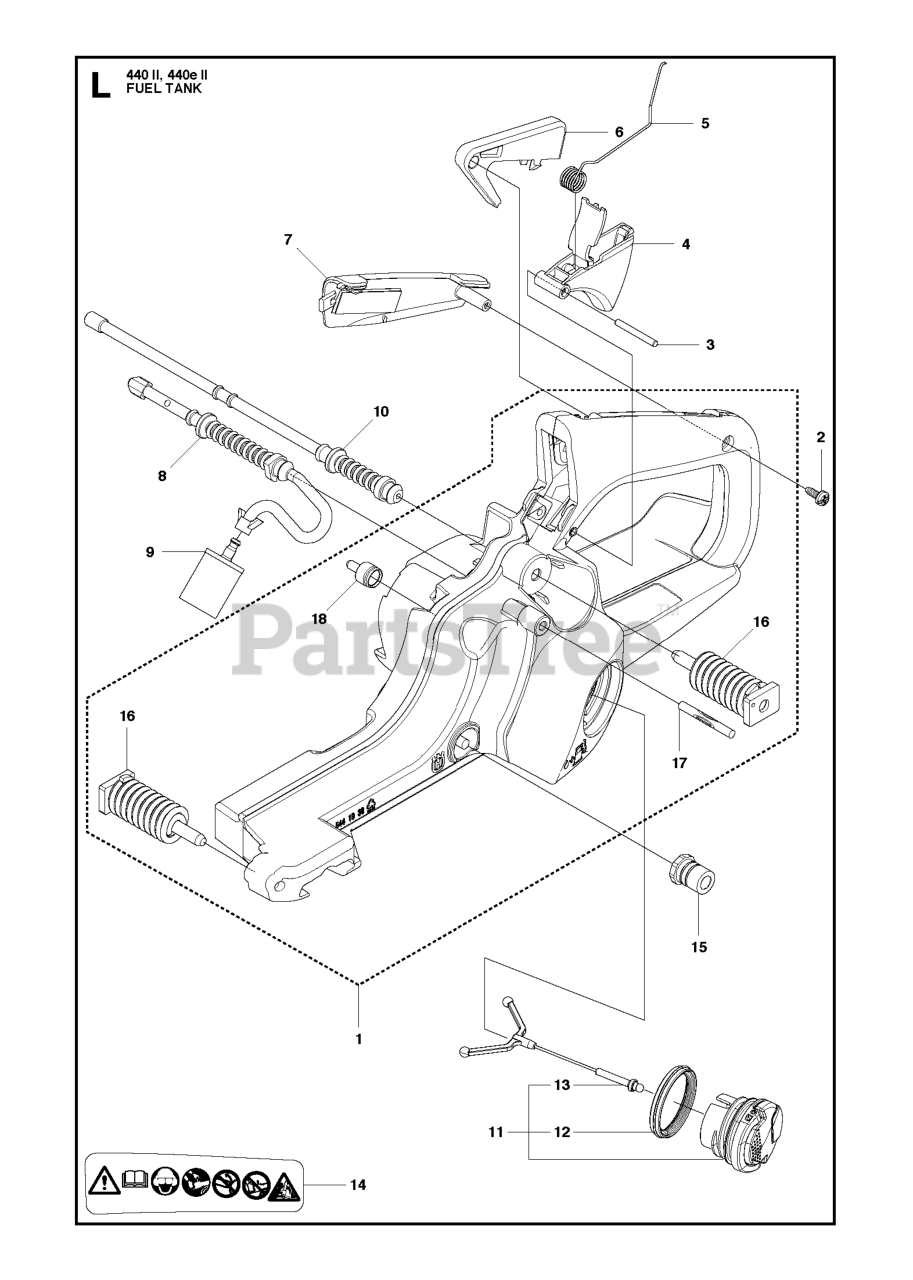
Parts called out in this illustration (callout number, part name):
1	FUEL TANK
4	THROTTLE CONTROL
6	TRIGGER LOCKOUT GREY
7	HANDLE INSERT
8	FUEL HOSE
9	RP FUEL FILTER
10	RETURN HOSE
11	TANK CAP ASSY
15	LATERAL SUPPORT
16	ANTIVIBRATION ELEMENT
17	GROOVED PIN
18	FUEL TANK VENT
